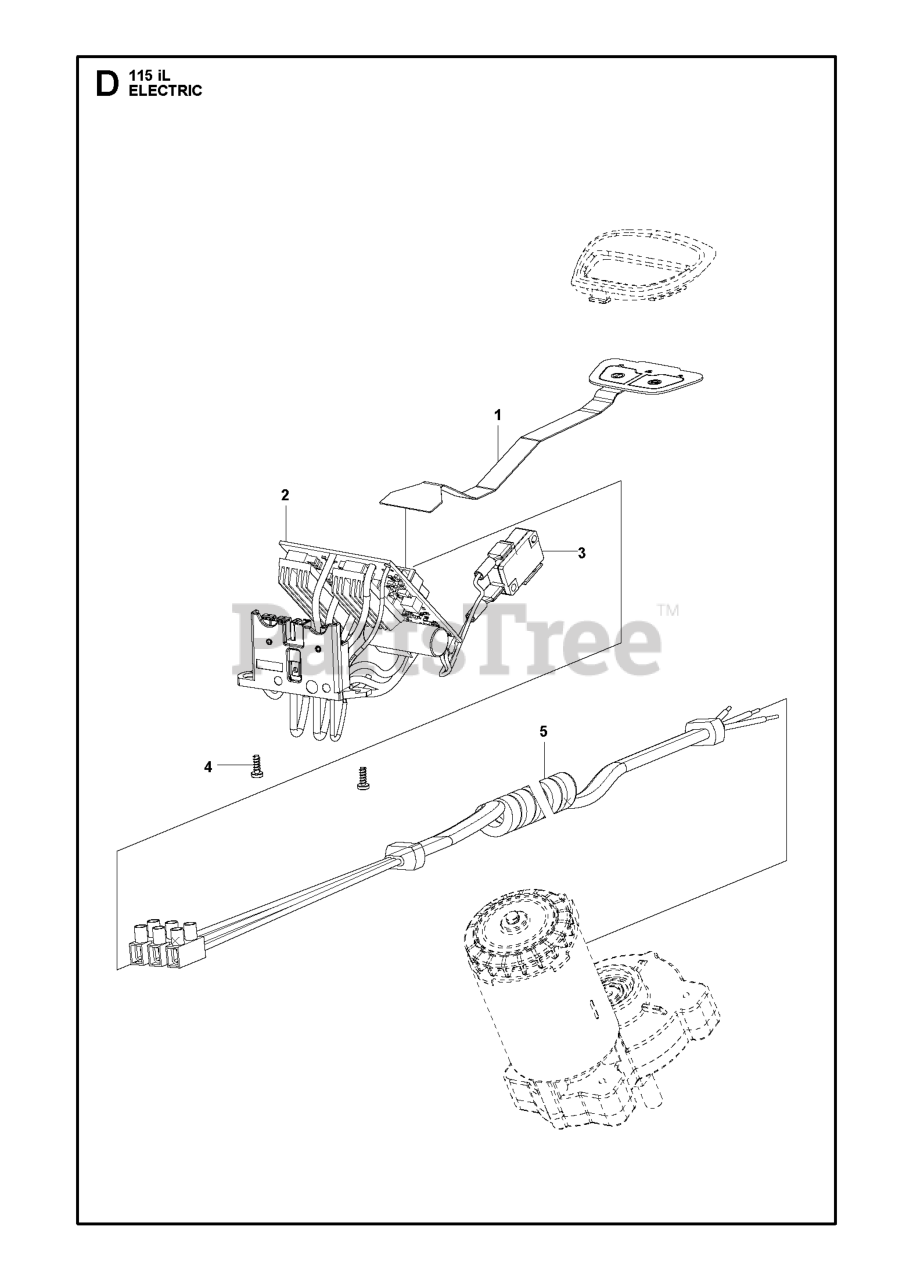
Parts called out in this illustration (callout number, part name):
1	KEYPAD TRIMMER 36V
2	CONTROL UNIT
4	SCREW ST3X8
